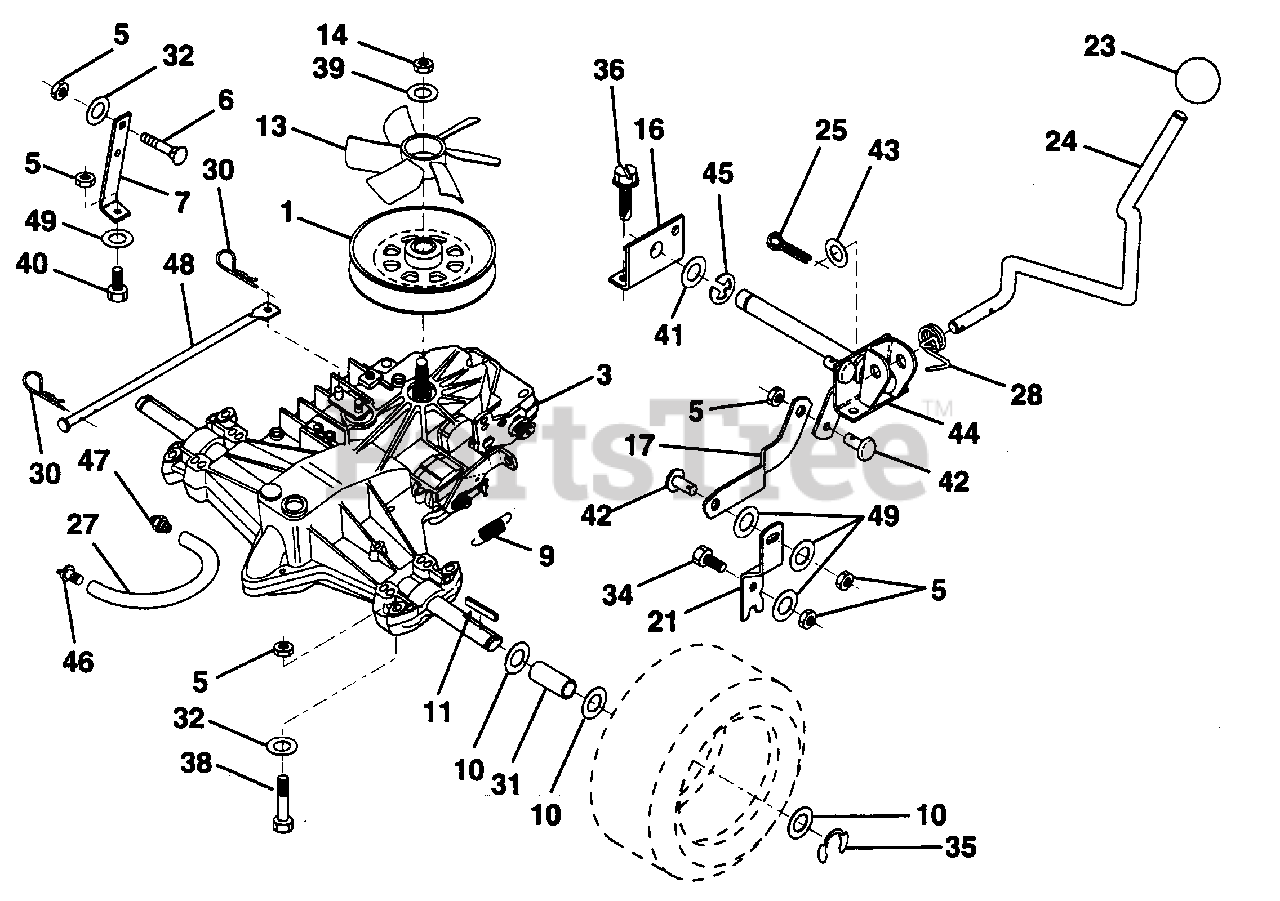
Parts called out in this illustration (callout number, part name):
3	Transaxle, Hydro 0310-0500
5	Nut Lock Hex w/Ins. 5/16-18
6	Bolt, Carriage
7	Strap, Torque
9	Spring Brake
10	Washer 25/32 x 1-1/4 x 16 Gauge
13	Fan, Transaxle, Hydro
14	Nut Lock 1/2-20 UNF x 3/4 x 7/16
16	Support, Shift Handle
23	Knob, Shifter
25	Pin, Cotter 1/8 x 1
28	Spring, Torsion
30	Retainer Spring
32	Washer 11/32 x 11/16 x 16 Ga.
34	Bolt Hex Hd. 5/16-18 x 1
36	Screw 1/4-20 x 1/2
38	Bolt, Hex Head 5/16-18 x 2-1/2
39	Washer 17/32 x 1-3/16 x 12 Ga.
40	Bolt Fin Hex 5/16-18 x 1-1/2
41	Washer 21/32 x 1-1/4 x 13 Ga.
43	Washer 17/32 x 3/4 x 16 Ga.
44	Pivot Shaft Assembly
48	Actuator, Bypass, Hydro
49	Washer 11/32 x 3/4 16 Ga.
